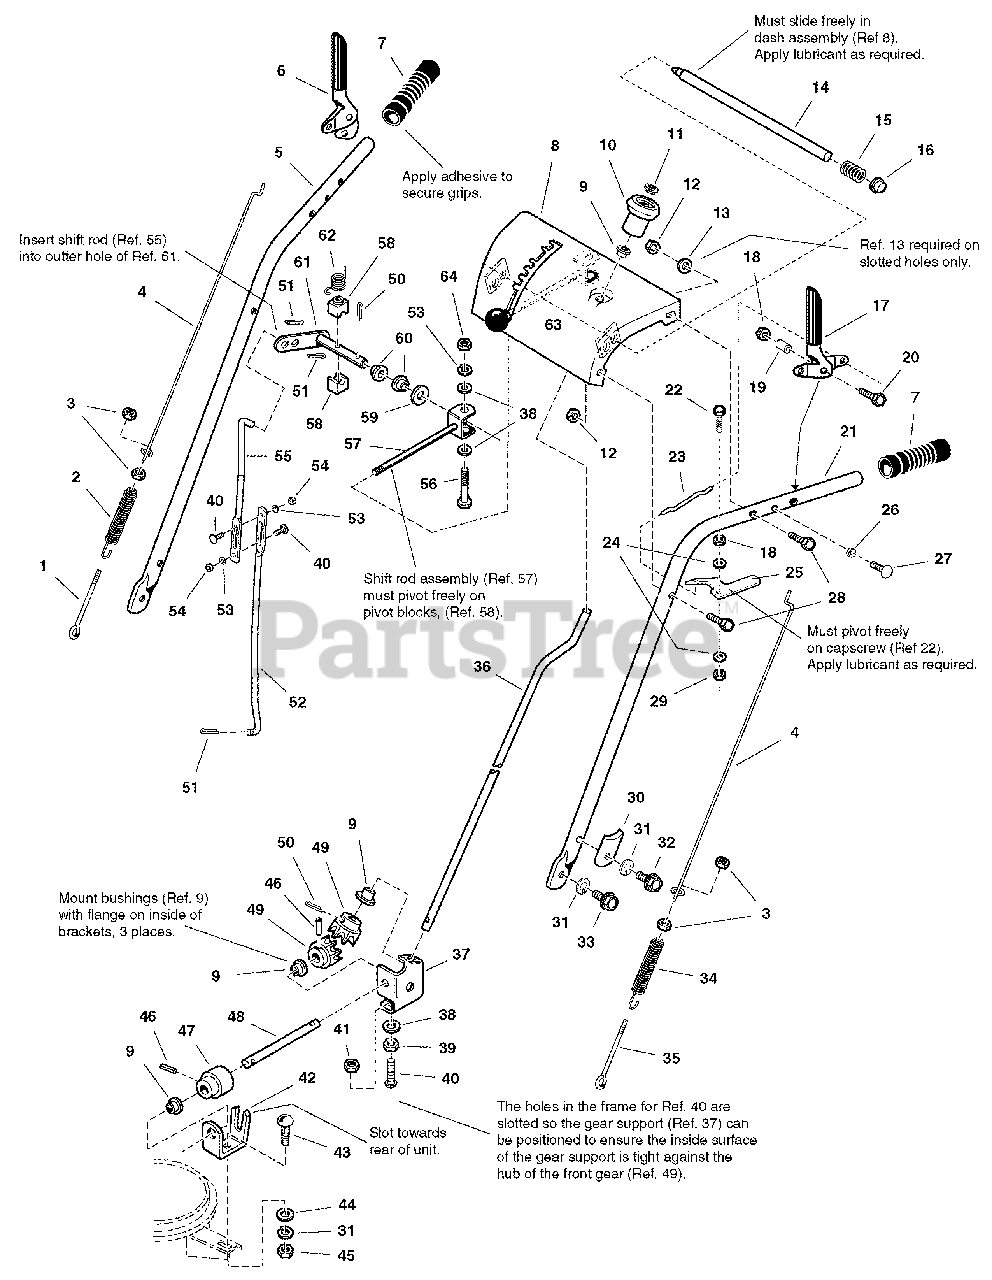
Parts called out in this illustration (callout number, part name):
1	ROD, Auger, 3 7/16 Long 10-24
2	SPRING, Extension, 3 7/16 Long
3	NUT, Hex Machine Screw, 10-24
4	ROD, Clutch/Traction, 23 1/8 Long
5	HANDLE, RH
6	HANDLE, Clutch, RH
7	GRIP, Black Vinyl
8	DASHBOARD & SUPPORT ASSEMBLY
9	BUSHING, 3/8
10	KNOB, Spinner, 2 1/2 Long
11	PUSH NUT, Pal, 3/8
12	NUT, Hex Lock ESNA Light, 5/16-18
13	WASHER, 5/16
14	ROD & SPRING ASSEMBLY, with Pin
15	SPRING, Compression, 1 7/8 Long
16	NUT, Push For 1/2 Inch Stud
17	LEVER, L.H. (Traction Drive Clutch)
18	NUT, Hex, Centerlock, 1/4-20
20	CAPSCREW, Hex Head, 1/4-20 x 1 1/2
22	CAPSCREW, Hex Head, 1/4-20 x 1 3/4
23	ROD, 5 3/4 Long
24	WASHER, 1/4
25	LEVER, Pivot
27	SCREW, Taptite, Pan Head, Torx, 1/4-20 x 3/4
28	CAPSCREW, Hex Head, 5/16 x 1 1/2
29	NUT, Hex Lock ESNA Light, 1/4-20
30	CLAMP, Tube Saddle
31	LOCKWASHER, Spring, 5/16
32	CAPSCREW, Hex Head, 5/16-18 x 1 3/4
33	CAPSCREW, Hex Head, 5/16-18 x 3/4
34	SPRING, Extension, Clutch Rod
35	ROD, Clutch, 6 5/16 Long
36	ROD, Chute Control, 27 Long
37	SUPPORT, Gear
38	WASHER, 1/4
39	PUSH NUT, 1/4
40	CARRIAGE BOLT, 1/4-20 x 5/8 G5
41	NUT, Hex Whiz Lock Flange, Small, 1/4-20
42	SUPPORT, Worm
43	CARRIAGE BOLT, 5/16 x 3/4 G5
44	WASHER, 5/16
45	NUT, Hex, 5/16-18
46	PIN, Spring 1/8 x 3/4
47	WORM, Chute, LH
48	ROD, Chute, 17 3/4 Long
49	GEAR, Powder Metal
50	PIN, Cotter
51	PIN, Cotter
52	ROD, Shift, 3/8 15 5/16
53	LOCKWASHER, Spring, 1/4
54	NUT, Hex, 1/4-20
55	ROD, Upper Shift, 12 1/2 Long
56	CAPSCREW, Hex Head, 1/4-20 x 2 1/4 G5
57	ROD & CLEVIS ASSEMBLY, Shift
58	BLOCK, Pivot, 3/4 x 3/4
59	WASHER, 1/2
60	BUSHING, 1/2
61	ROD & ARM ASSEMBLY, Pivot
62	SPRING, Torsion, 1/2 Long
63	KNOB
64	NUT, Hex ESNA, 1/4-20, Yellow
